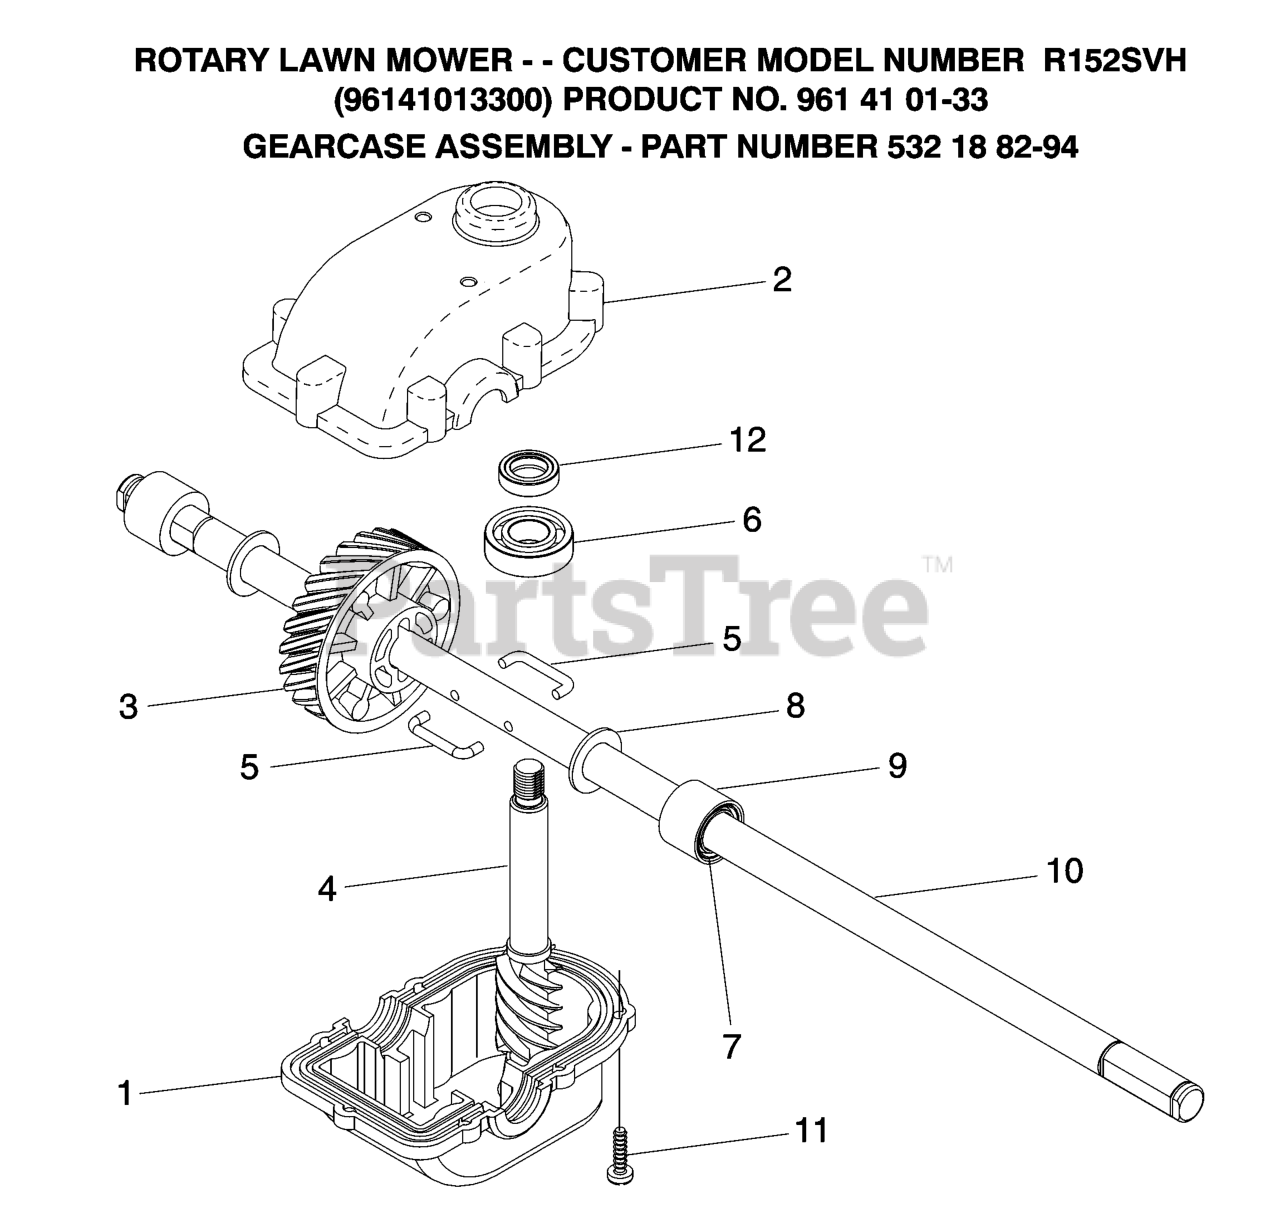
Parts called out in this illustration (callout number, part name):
1	CASE, LOWER
2	GEARCASE.HOUSING
3	GEAR.24.TOOTH.WALK.MOWER
5	WIRE, FORMED (15966)
7	SEAL.OUTPUT.SHAFT
10	SHAFT OUTPUT
12	SEAL INPUT SHAFT
